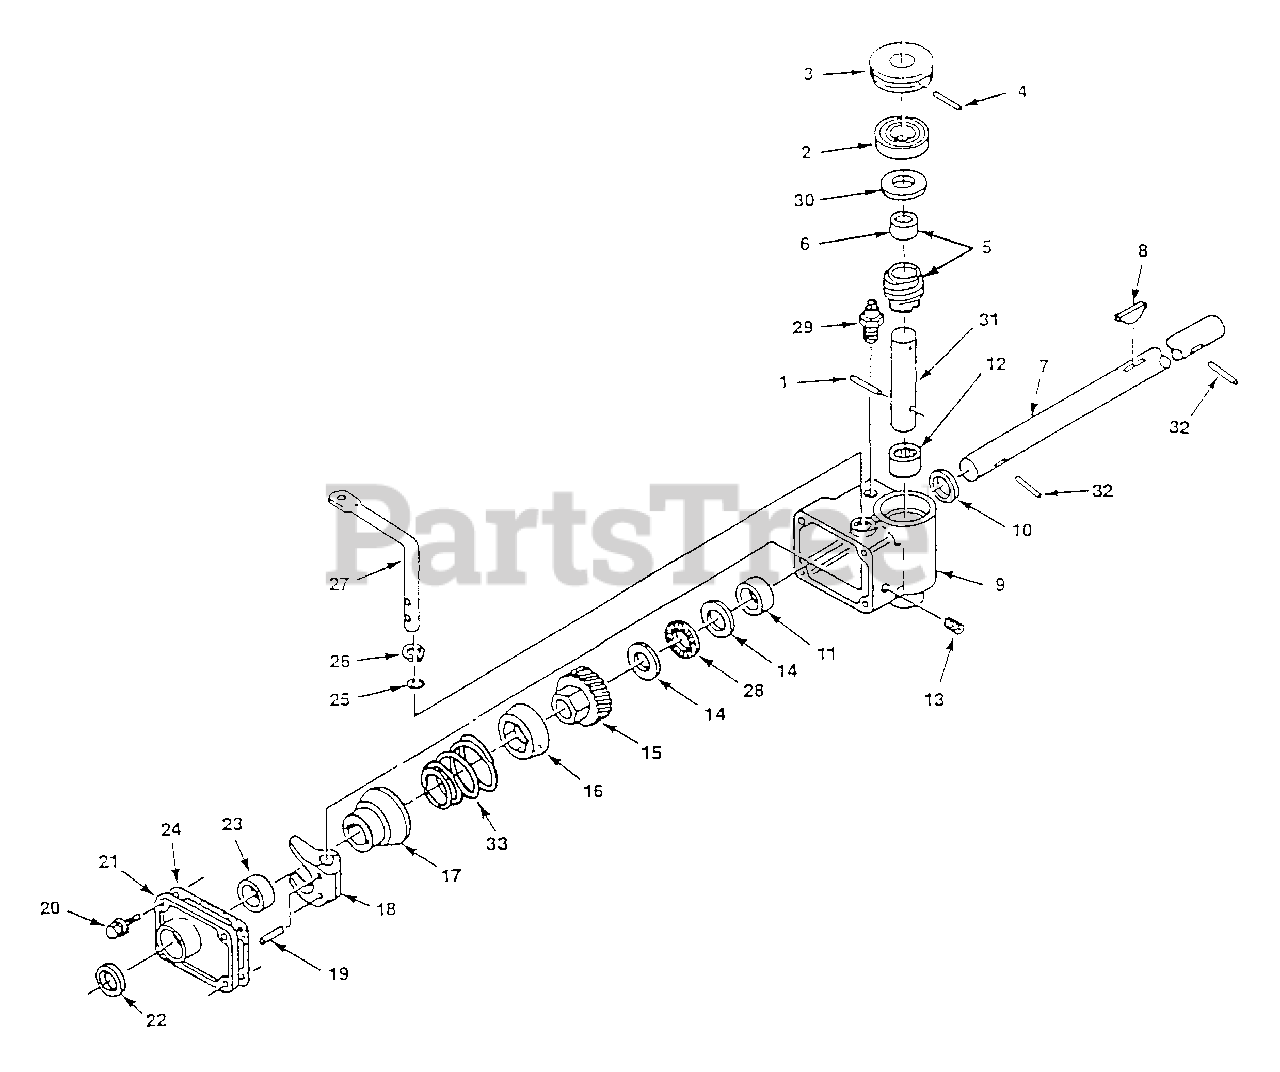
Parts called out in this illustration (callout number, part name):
1	Pin - Roll 3/16 x 7/8
2	Bearing - Bail
3	Pulley - Gear box
4	Pin - Roll 3/32 x 1 1/4"
5	WORM & SPACER
6	SPACER - Worm
7	SHAFT - Drive
9	HOUSING - Gear box
11	BUSHING - Sleeve
12	BEARING - Needle
13	PLUG - Pipe
14	RACE - Thrust
15	GEAR - Helical
16	CONE - Friction
17	DRUM - Clutch
18	FORK - Shift
19	PIN - Groove
20	SCREW - 1/4-20 x 7/8"
21	COVER - Gear Box
23	BUSHING - Sleeve
24	GASKET - Cover
26	TRU-ARC RING
27	LEVER - Shift
28	BEARING - Needle
31	WORM - Shaft
32	PIN - Roll 1/8" x 7/8"
33	SPRING - Clutch
